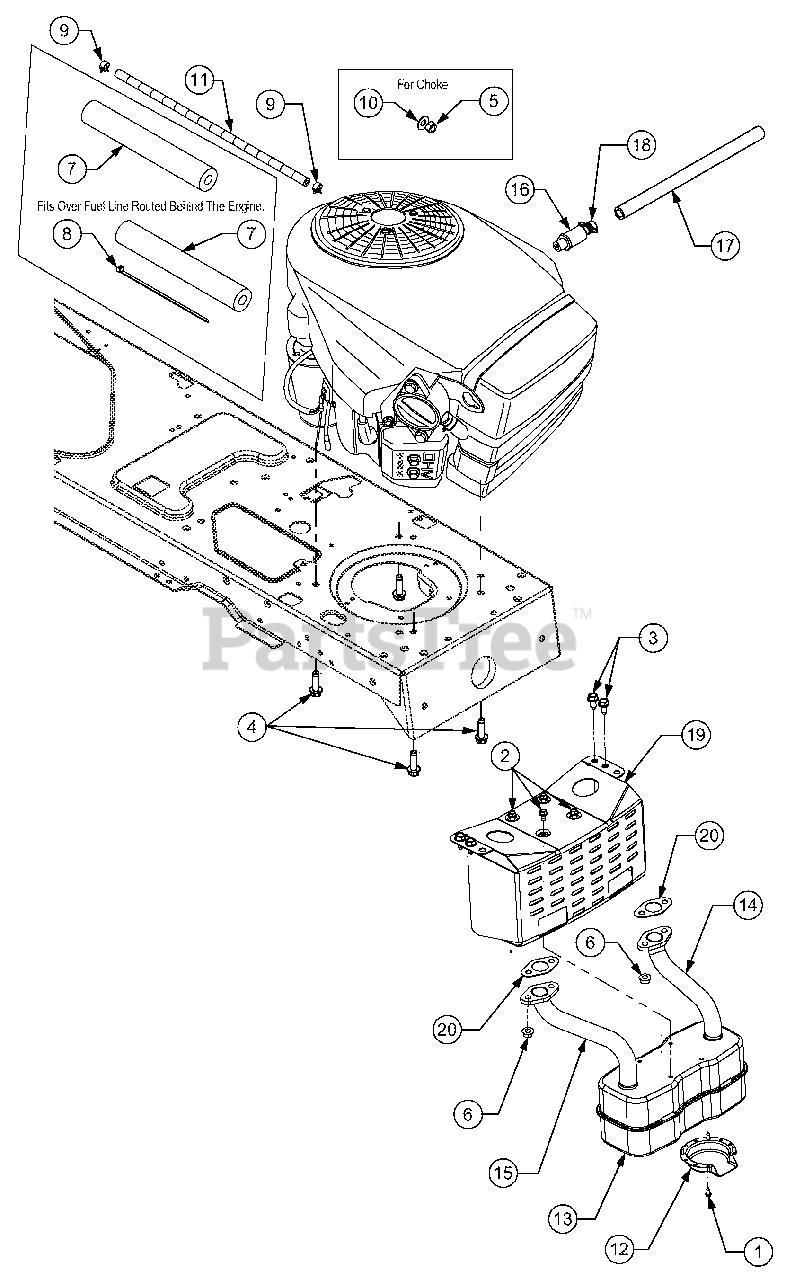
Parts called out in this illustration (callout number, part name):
1	Screw, #8-18, 0.500
2	Screw, Self-tapping, 1/4-20, 0.500
3	Screw, Hx. Wash. Hd. Tapp 5/16-12 x .75
4	Screw, Hx. Wash. Hd. Tapp 3/8-16 x
5	Nut, Hex, 3/8-16, Gr8
6	Nut, M8, 1.25-6h, Flange
7	Foam, .625 x 1.50 x 10.0 Lg
8	Cable, Tie, 3/16 x .05 x 7.4
9	Clamp, Hose, .490 Dia.
10	Washer, Flat, .406 x .875 x .059
11	Hose, Fuel Line
12	Deflector, Muffler
13	Muffler, Dual Inlet
14	Pipe, Exhaust, LH
15	Pipe, Exhaust, RH
16	Drain, Oil
17	Hose, Extension, Oil Drain
18	Cap, Oil, Drain
20	Gasket, Exhaust
